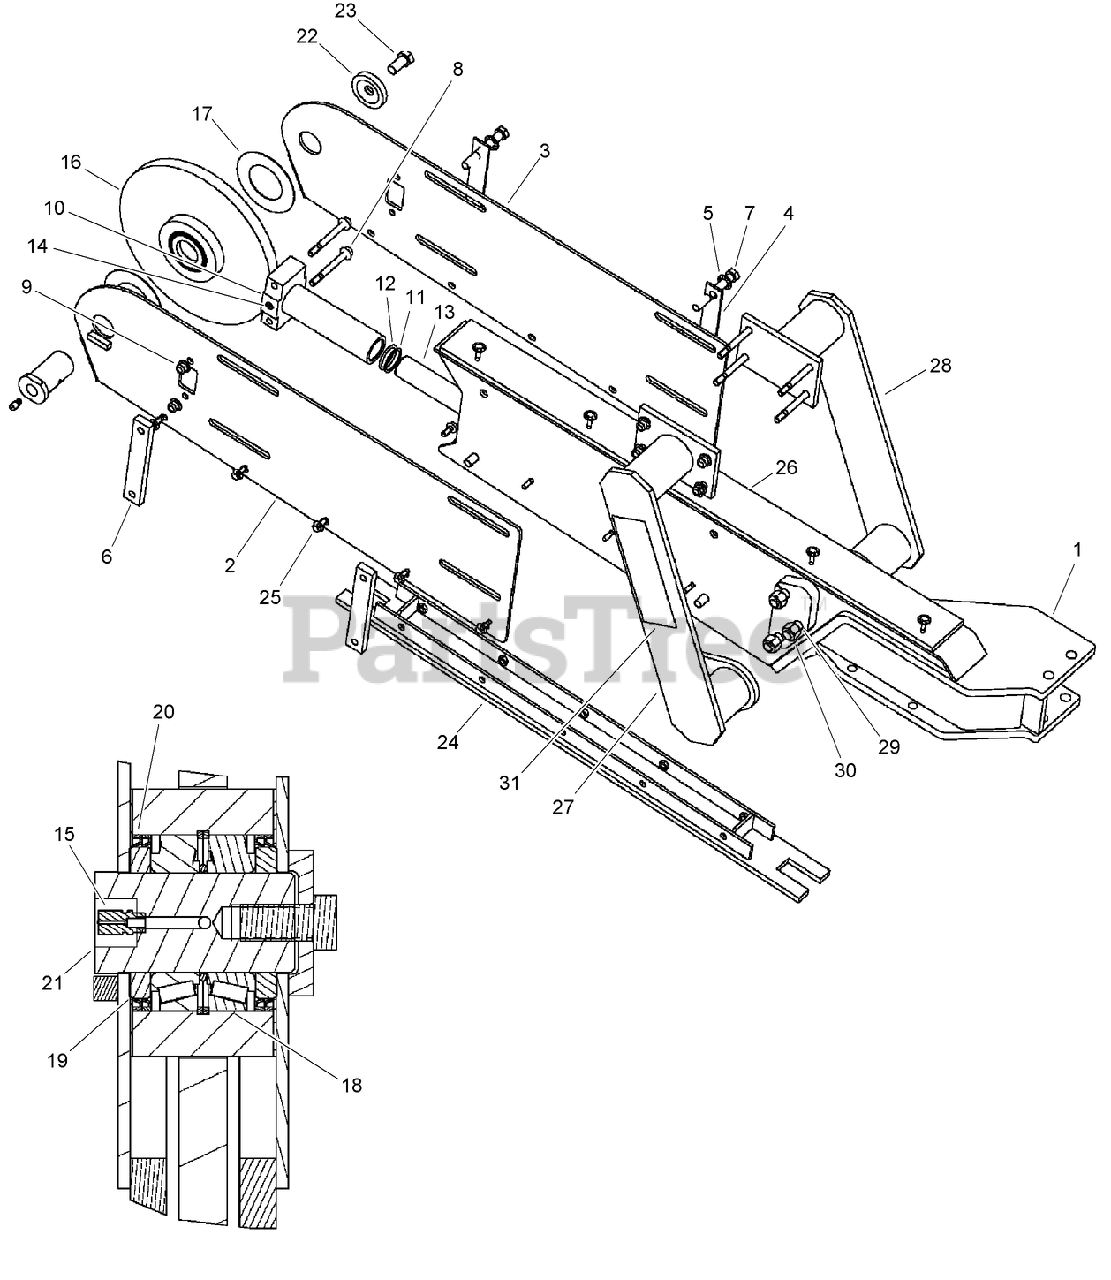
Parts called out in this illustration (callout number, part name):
1	BOOM-Rock, 4\
2	PLATE-Boom End (RH)
3	PLATE-Boom End (LH)
4	BAR-Clamp
5	WASHER-LOCK
6	BAR-Tapped
8	BOLT-HHF
9	NUT-HHF, LOCK
10	CYLINDER-Boom End
11	WASHER-BACKUP
13	ROD-BOOM, END (CYLINDER)
14	PLUG-BLEED
15	FITTING-LUBE, STRAIGHT
16	BOLLER-Boom End
17	WASHER-BOOM, END (ROLLER)
18	BEARING KIT
19	SPACER-bearing
20	SEAL-ROLLER
21	PIN-BOOM
24	CHANNEL-Wear Pad, 4\ Boom
25	SCREW-FLANGE
26	BAR-Wear Pad, Upper, 4\ Boom
27	MOUNT-Crumber RH
28	MOUNT-Crumber LH
30	NUT-Prev Trq 3/4 GRC CAD Direct
31	DECAL-Danger, Trencher Entanglement Hazard
